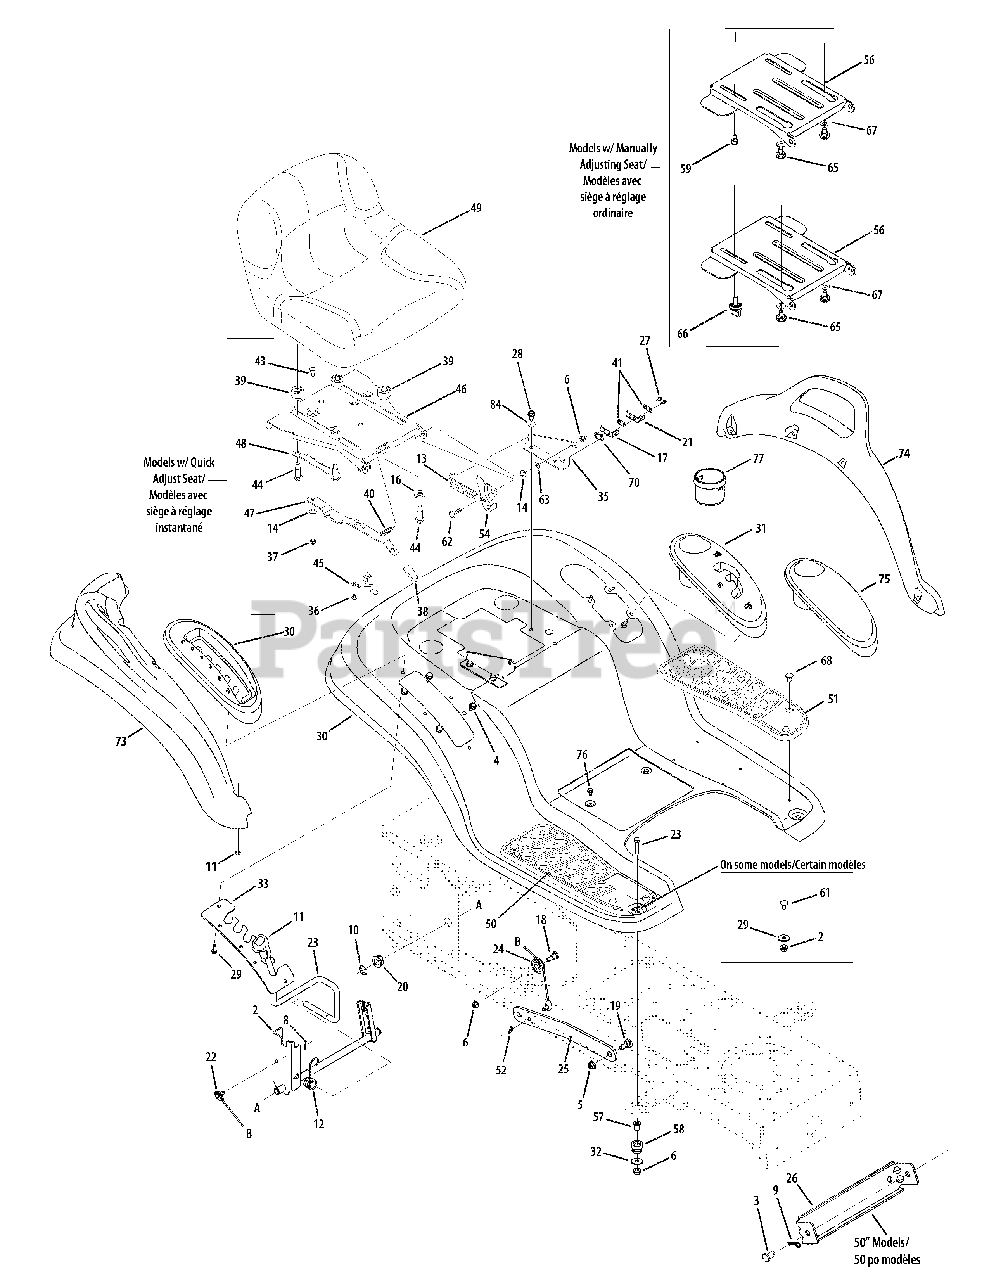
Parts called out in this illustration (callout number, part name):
1	Deck Stabilizer Rod
4	S-Tapp Scr 5/16-18 x .75
5	Hex Flange Locknut 3/8-16 Gr. F,Nylon
6	Hex Flange Locknut 5/16-18 Gr. F Nylon
7	Hex Nut, 1/2-13
8	Int. Cotter Pin 5/16 Dia.
9	Internal Cotter Pin .080 x 1.5625
12	Torsion Spring
13	Extension Spring .84 x 4.6
14	Cupped Wash. .345 ID x .88 OD x .060
16	Flat Washer .531 ID x 1.062 OD x .134
17	Spring Switch, Inner
18	Shoulder Scr. .437 Dia x .47
19	Shoulder Screw .500 x .25
20	Hex Flange Bearing .630 ID
21	Spring Switch, Outer
22	Lift Cable, 16.16
24	Roller Pulley
27	Insulator Plate
28	S-Tapp Scr 5/16-18 x .75
28	Screw 5/16-18 x .75 (601)
29	Hex Scr. 1/4-15 x .75
30	Lift Lever Cover
31	Shift Lever Cover w/Cup Holder
32	Flat Washer .344 ID x 1.0
36	Hex B-Tapp Wash Scr #10-16 x .375
37	Hex Flange Locknut 1/4-20 Gr. F Nylon
38	Seat Adjuster Grip
40	Compression Spring 1.5" Lg
41	Cupped Washer .340 ID x .872 OD x .060
43	Shoulder Screw .340 x .285: 1/4-20
44	Shoulder Screw, .50 x .925, 3/8-16
48	Seat Adjustment Selector
49	Seat 15.279" High, High Back-Blk
49	High Back Seat YM Yellow
52	Cotter Pin 3/32 dia. x 1.00 Lg.
54	Seat Lift Bracket
57	Grommet
58	Flg. Spacer .3125 x .4375 x .625
59	Hex Wash Hd Scr. 3/8-16 x .625 Gr. 5
61	Ratchet Clip .25 Dia.
62	Shoulder Bolt .437 Dia. x .268
63	Push Speed Nut
65	Shoulder Spacer .625 x .175, 3/8-16
66	Knob, 3/8-16 x .625
67	Flat Washer .406 x .875 x .059
68	Carriage Bolt 5/16 x 18 x .75" Lg.
69	Hex TT Scr. 5/16-18 x .875
70	Insulator Plate
71	Carriage Bolt 1/4-20 x 1.00" Lg.
72	Sems Hex Nut 1/4-20
73	RH Fender Flare
74	LH Fender Flare
75	Cover w/Cup Holder
76	Hex Wash S-Tapp Scr 1/4-20 x .50
77	Cup Holder, Style 7
78	Hex Nut 1/2-13
79	Flat Washer .510 x 1.12 x .06
80	Shoulder Screw .50 x 2.230:3/8-16
81	Shoulder Screw .625 x .175: 3/8-16
84	Ext. Lockwasher 5/16 ID
87	Spring Switch
88	Insulator Nut Plate
